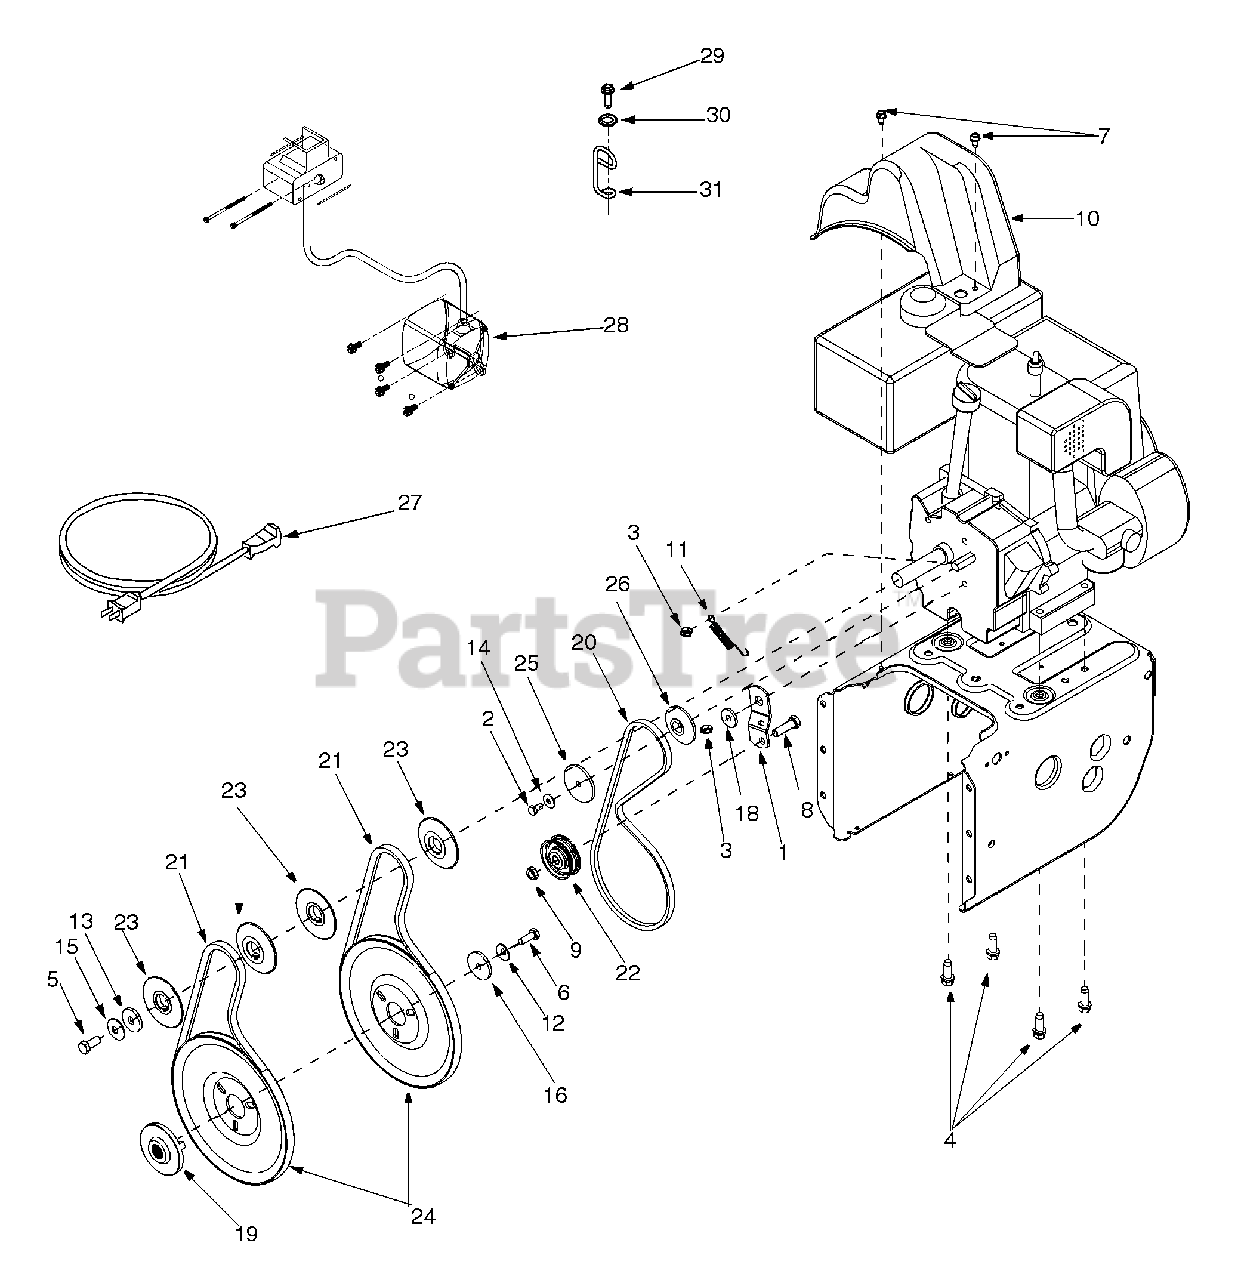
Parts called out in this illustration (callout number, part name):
3	Hex Scr w/ Patch: 5/16-24 x 0.75"
4	Hex Washer Head Sems Screw
5	Hex Bolt 3/8-24 x .875" Gr.8
6	Hex Scr w/ Patch: 5/16-24 x .875"
7	Hex Washer Head TT
8	Hex Screw: 3/8-16 x 1.0"
9	Top Lock Jam Nut: 3/8-16
10	Belt Cover
11	Extension Spring
12	Bellevile Washer
13	Flat Washer
14	Bell Washer
15	Bell Washer
16	Flat Washer
18	Shoulder Spacer
19	Adapter Pulley
20	V-Belt
21	Belt
22	Flat Idler
23	Pulley Half
24	Auger Pulley
25	Pulley Half
26	Pulley Half
27	Extension Cord
28	Electric Start Kit
29	Lock Nut 1/4-20
30	Flat Washer .28 ID x .74 OD
31	Cable Guide
